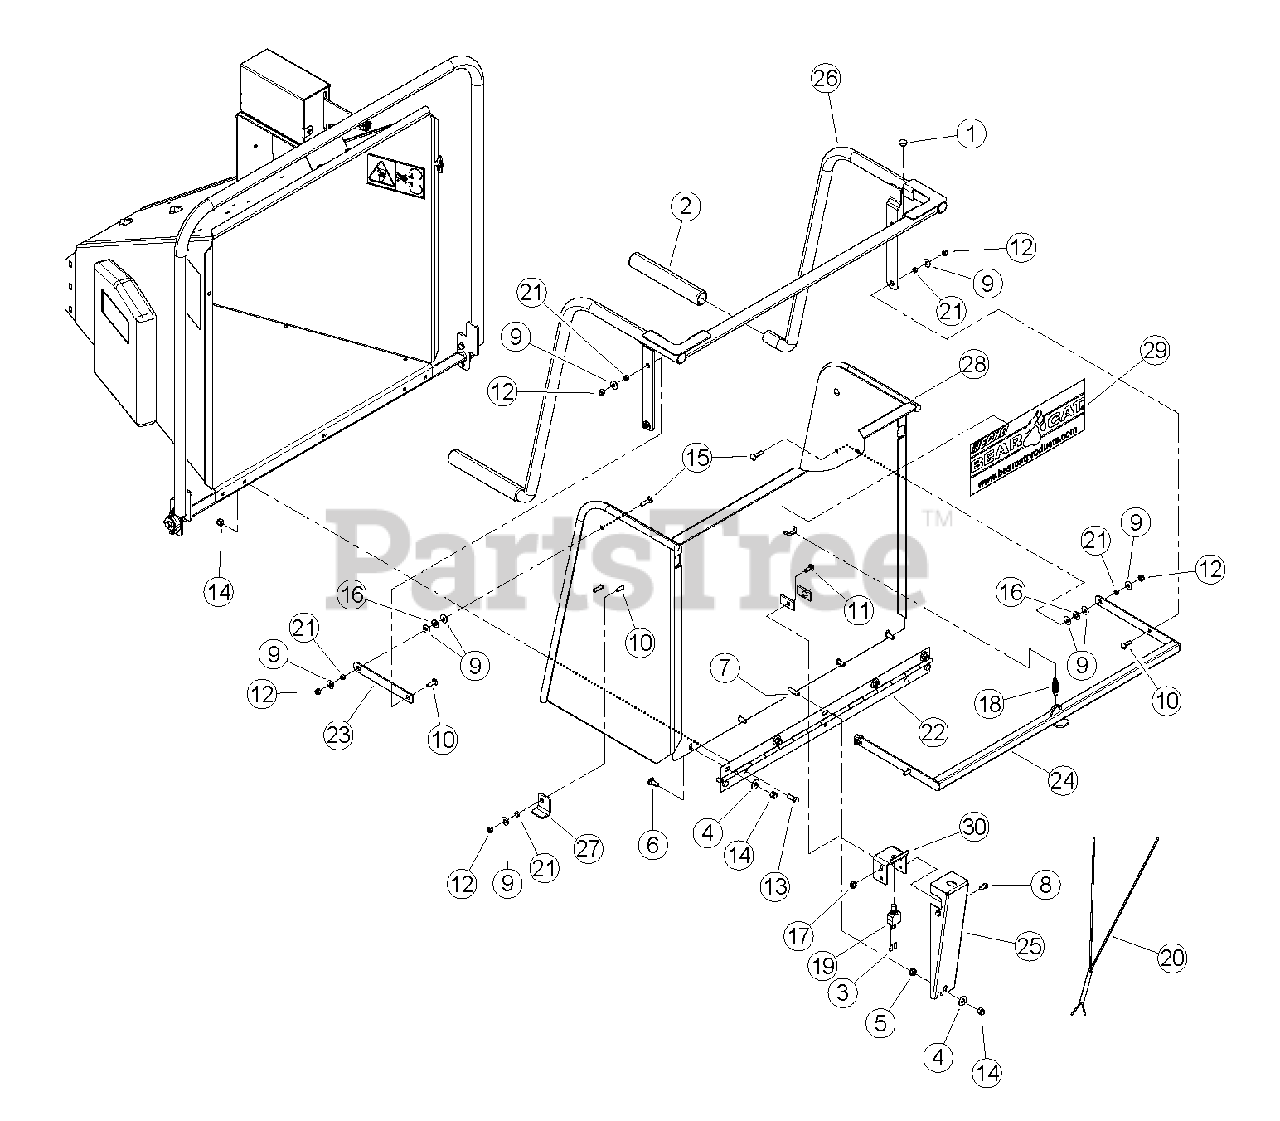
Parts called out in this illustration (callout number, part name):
1	BUMPER, RUBBER
2	GRIP, 1.219 X 10.00
3	CONNECTOR, 1/4 QD MALE
4	WASHER, 3/8 FLAT ZP
5	NUT, 3/8 SERRATED FLANGE ZP
6	BOLT, 3/8 X 1 CRG GR5 NC ZP
7	BOLT, 3/8 X 1-1/2 CRG GR5 NC ZP
8	SCREW, 11/32 X 7/8 HWH AB THREAD ZP
9	WASHER, 5/16 FLAT ZP
10	BOLT, 5/16 X 1 CRG GR5 ZP
11	BOLT, 5/16 X 7/8 CRG GR5 NC ZP
12	NUT, 5/16 NE NYLOCK ZP
13	BOLT, 3/8 X 1-1/4 HEX HD GR5 ZP
14	NUT, 3/8 NE NYLOCK ZP
15	BOLT, 5/16 X 1-1/4 CRG GR5 ZP
16	WASHER, 5/16 ID. X 7/8 OD. NYLON FLAT
17	NUT, 5/16-18 NYLOCK-FLANGE
18	SPRING 1/2 X 2.00 LG,ZP
19	SWITCH, N/C MOMENTARY PLUNGER
19	SWITCH, MOMENTARY IP67 NORMALLY ON
20	HARNESS, SAFETY BAR
21	SPACER, IDLER PIVOT
22	HINGE, EXTENSION TRAY
23	LINK, PARALLEL
24	WELDMENT, KNEEBAR PIVOT
25	SHIELD, KNEEBAR SWITCH
26	WELDMENT, KNEEBAR
27	LOCK, SAFETY BAR
28	ASSEMBLY, EXTENSION TRAY SERVICE PART
29	DECAL, BEARCAT WEB
30	BRACKET, SWITCH
